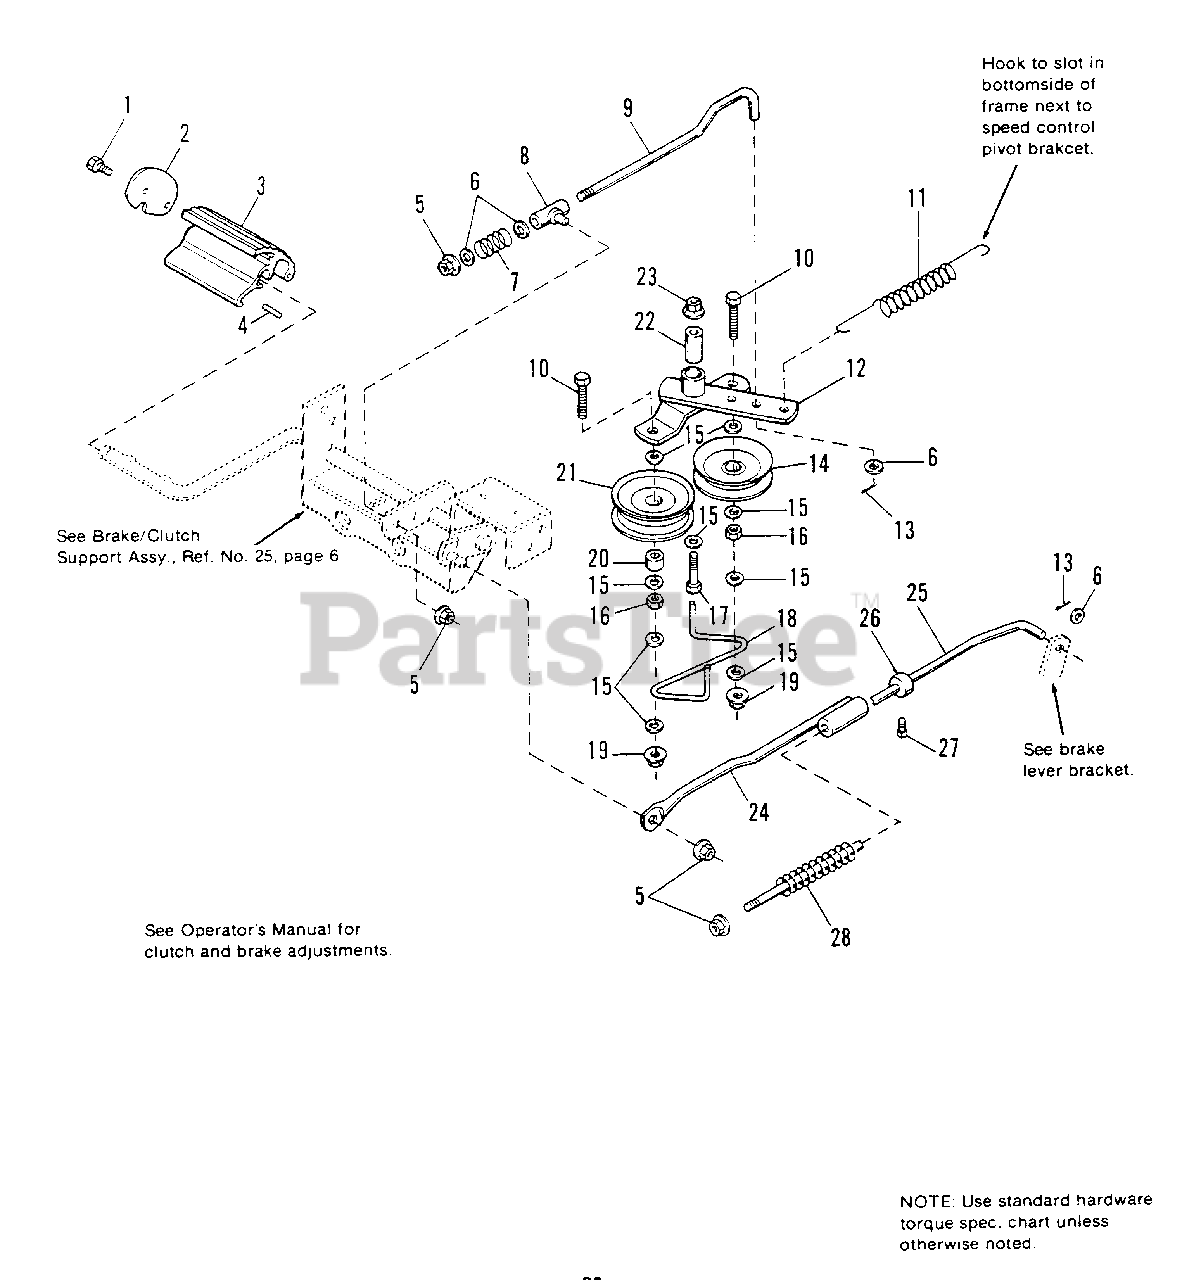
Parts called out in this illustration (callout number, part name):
1	SCREW, Taptite, 1/4-20 x 5/8
2	PLATE, End
3	PEDAL, Brake
4	DAMPER, Rubber
5	NUT, Flange Lock, 5/16-18
7	SPRING, Compression
8	GUIDE ASSY., Rod
9	ROD, Clutch
10	CAPSCREW, 3/8-16 x 2, Full Thread
11	SPRING, Tension
12	BRACKET ASSY., Idler
13	PIN, Cotter
14	PULLEY, V-Idler
15	WASHER
16	NUT, Jam, 3/8-16
17	CAPSCREW, 3/8-16 x 2
18	GUIDE, Belt
19	NUT, Hex, 3/8-16
20	SPACER (For Flat-Side Pulley)
21	PULLEY, Flat-Side
23	NUT, Whiz Flange
24	ROD ASSY., Brake
25	ROD, Brake
26	COLLAR, Set
27	SET SCREW, Sq. Hd.
28	SPRING, Compression
